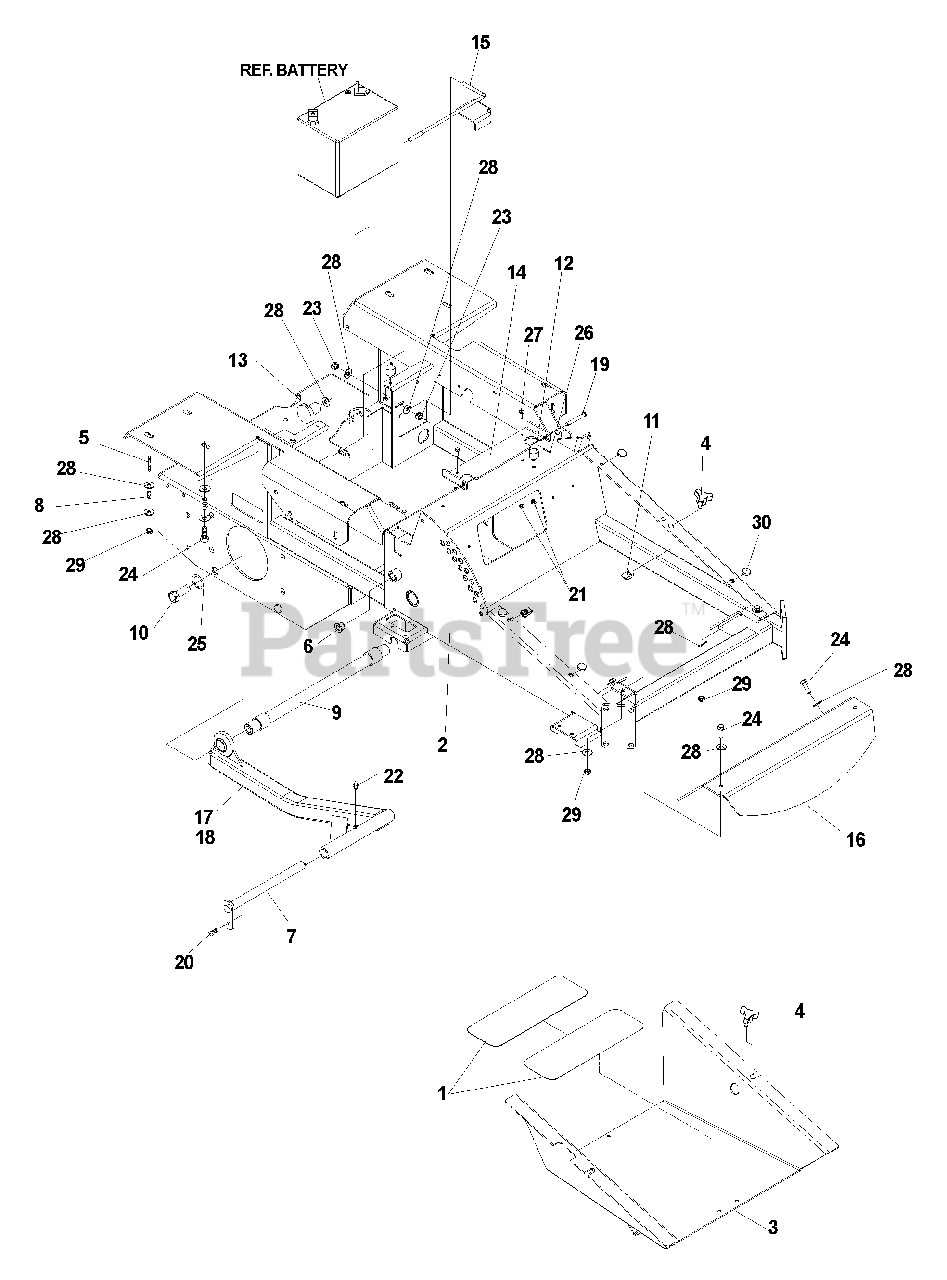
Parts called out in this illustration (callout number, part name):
1	PAD-ADRASIVE
2	FRAME W/DECALS
3	FOOT PLATE W/DECALS
4	KNOB W/STUD
5	TANK-STUD FUEL
7	PIN, PIVOT
8	SPRING, FUEL TANK
9	STRUT MOUNT
10	HCS, 5/8-11 X 2, GR5
11	NUT, 5/16-18, U-TYPE
12	MOUNT-STUD-PLATE
14	SEAT BRACKET W/DECAL
15	BATTERY HOLD DOWN
17	STRUT, RIGHT
18	STRUT, LEFT
19	CLEVIS PIN, 3/8
20	HCS, 5/16-18 X 3/4, GR5
21	NUT, 1/4-20, NYLOC
22	ZERK, STRAIGHT, 1/4-28
23	NUT, 5/16-18, CENTERLOCK
24	HCS, 5/16-18 X 1, GR5
25	LOCKWASHER, 5/8
26	PIN COTTER, 1/8 X 3/4
27	HCS, 1/4-20 X 3/4, GR5
28	WASHER, 5/16
29	NUT, 5/16-18, NYLOC
30	GROMMENT, BUMPER
